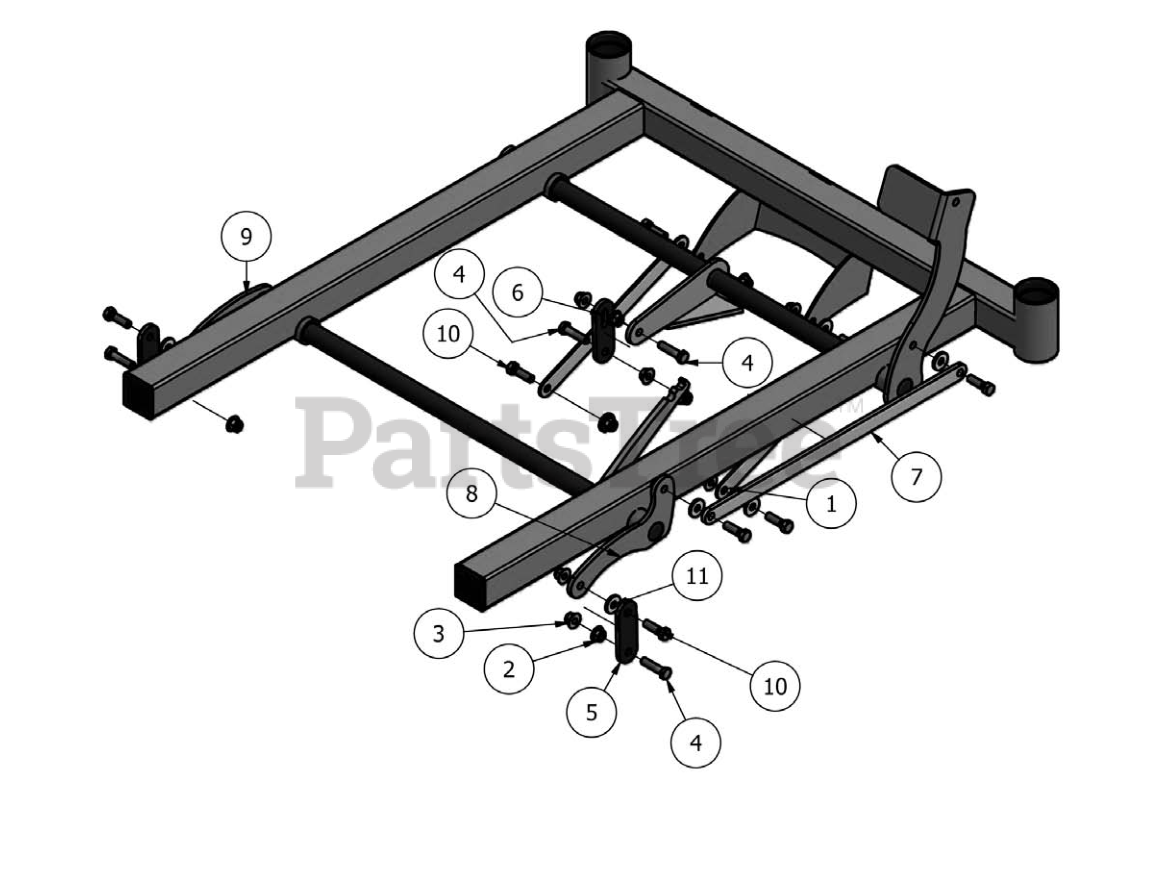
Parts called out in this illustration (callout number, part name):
1	MZ Front Arms
2	3/8-16 Hex flange Nut Zinc w/Serrations
3	3/8 Nylock Flange Nut
4	3/8-16 x 1-1/2 GR5 Hex Bolt
5	Deck Spacer (Rear)
6	Deck Spacer (Front)
7	Deck Linkage Rod
8	MZ Deck Pivot Lever Right Side
9	MZ Deck Pivot Support Left Side
10	3/8-16 x 1-1/4 GR 5 Hex Bolt Zinc
11	.360 ID Plastic Washer
